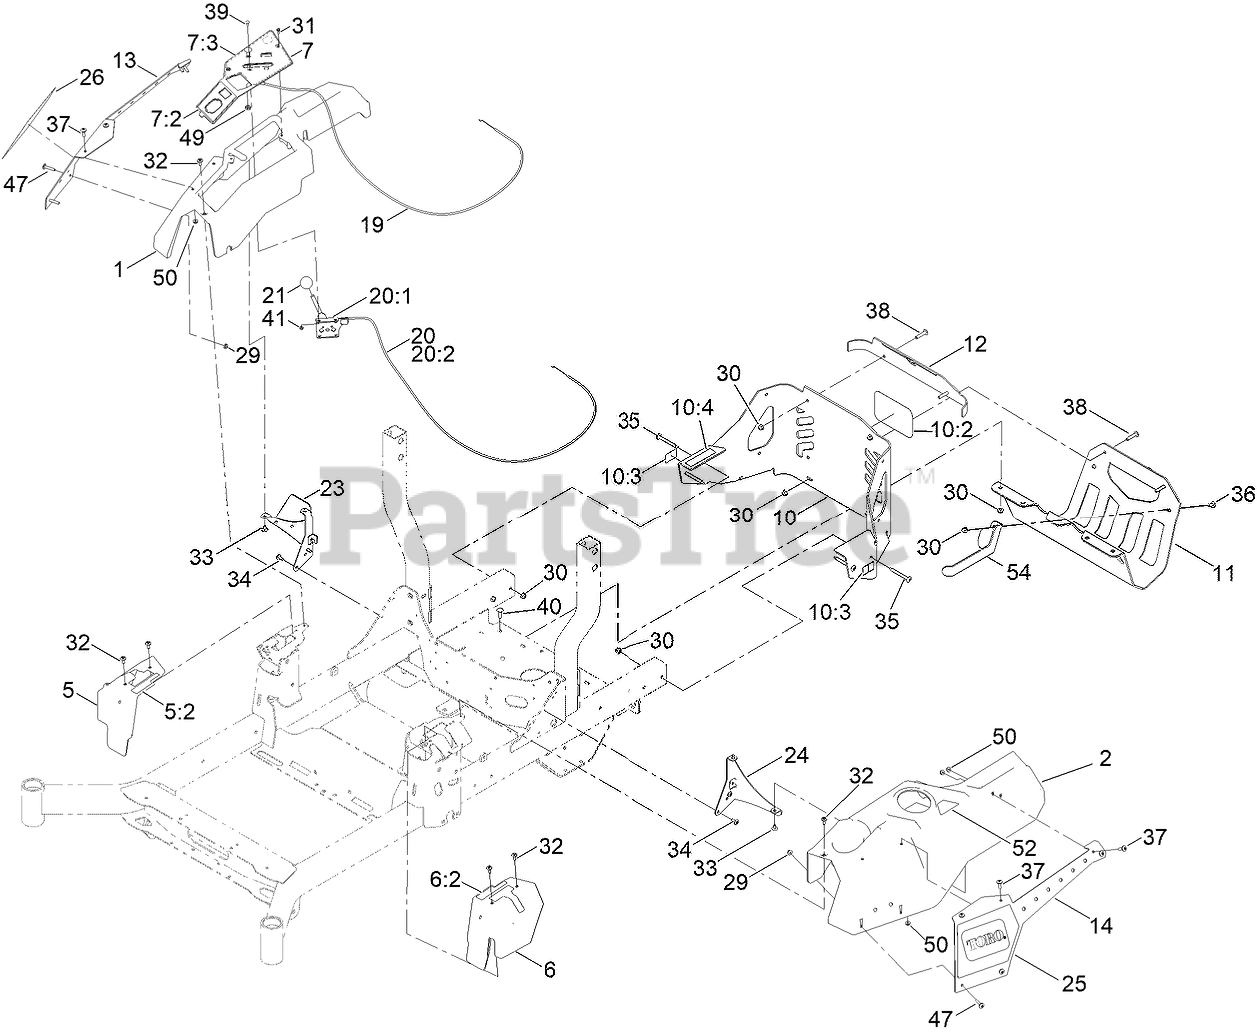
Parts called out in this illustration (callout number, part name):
1	CONSOLE-RH
2	CONSOLE-LH
5	COVER-CONTROL, MOTION (RH)
5:2	DECAL-CONTROL, MOTION (RH)
6	COVER-CONTROL, MOTION (LH)
6:2	DECAL-CONTROL, MOTION (LH)
7	CONTROL PANEL ASM
7:2	DECAL-PANEL, CONTROL
7:3	DECAL - PANEL CONTROL
10	REAR GUARD ASM
10:2	DECAL
10:3	DECAL-WARNING
10:4	DECAL-ARRESTOR, SPARK
11	GUARD-MUFFLER [BLACK]
12	TRIM-UPPER REAR
13	COVER, POD RH
14	COVER-LH
19	CABLE-CHOKE CONTROL
20	THROTTLE CONTROL ASM
20:1	LEVER-THROTTLE
21	KNOB-BALL
23	SUPPORT-CONSOLE, RH
24	BRACKET-CONSOLE, LH
25	DECAL-PLATE, LH
26	DECAL-PLATE, RH
29	NUT-HF
30	NUT-HF, NI
31	SCREW-HWH
32	SCREW-SHOULDER
33	SCREW-TORX
34	SCREW-TORX
35	SCREW-TORX
36	SCREW-TORX
37	SCREW-TRUSS
38	SCREW-TORX
39	BOLT-CARR
40	SCREW-CARR
41	NUT-LOCK, NI
47	SCREW-TRUSS
49	NUT-HJ
50	NUT-KEPS
52	DECAL-FILL, FUEL
54	BRACKET-GUARD, MUFFLER
